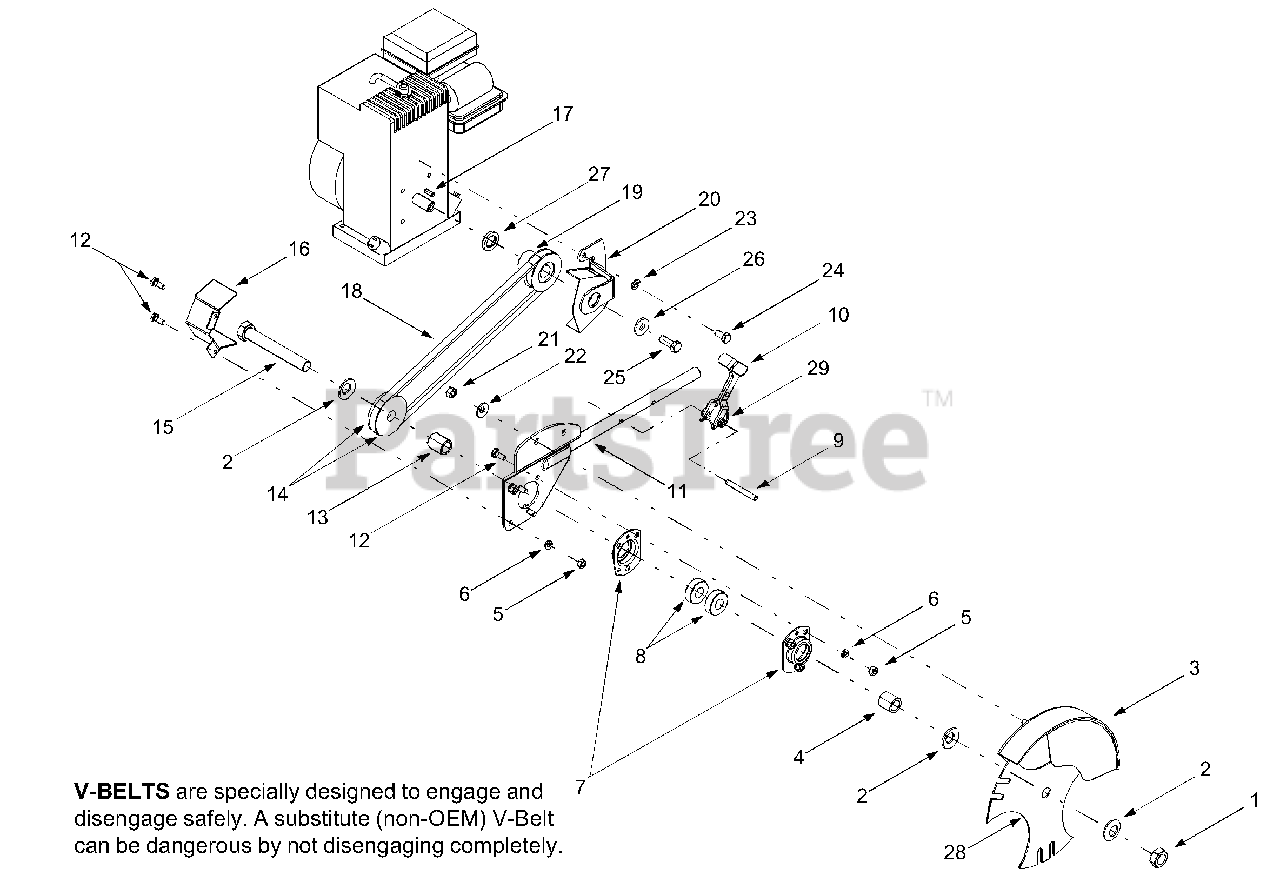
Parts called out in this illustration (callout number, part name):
1	Hex Jam Nut, 5/8-18
2	Bell Washer, .64 x 1.25 x .18
5	Hex Nut, 1/4-20
6	Lock Washer, 1/4
7	Bearing Housing
8	Ball Bearing, .62 x 1.38 x .44
9	Spirol Pin, 1/4 x 2.0
10	Adjustment Lever Assembly
13	Spacer, .635 x .88 x 1.03
14	Sheave, .6255 x .6295
15	Hex Cap Screw, 5/8-18 x 4.5
17	Square Key, 3/16 x .75
18	V-belt, 3/8
19	Engine Pulley, 3/8 x .75 x 2.38
22	Belleville Washer, .340 x .872
23	Lock Washer, 5/16
24	Hex Cap Screw, 5/16-24 x .625
25	Hex Cap Screw, 3/8-24 x 1.0
26	Flat Washer, .385 x 1.0 x .135
27	Spacer, .753 x 1.25 x .175
29	Double-torsion Spring
